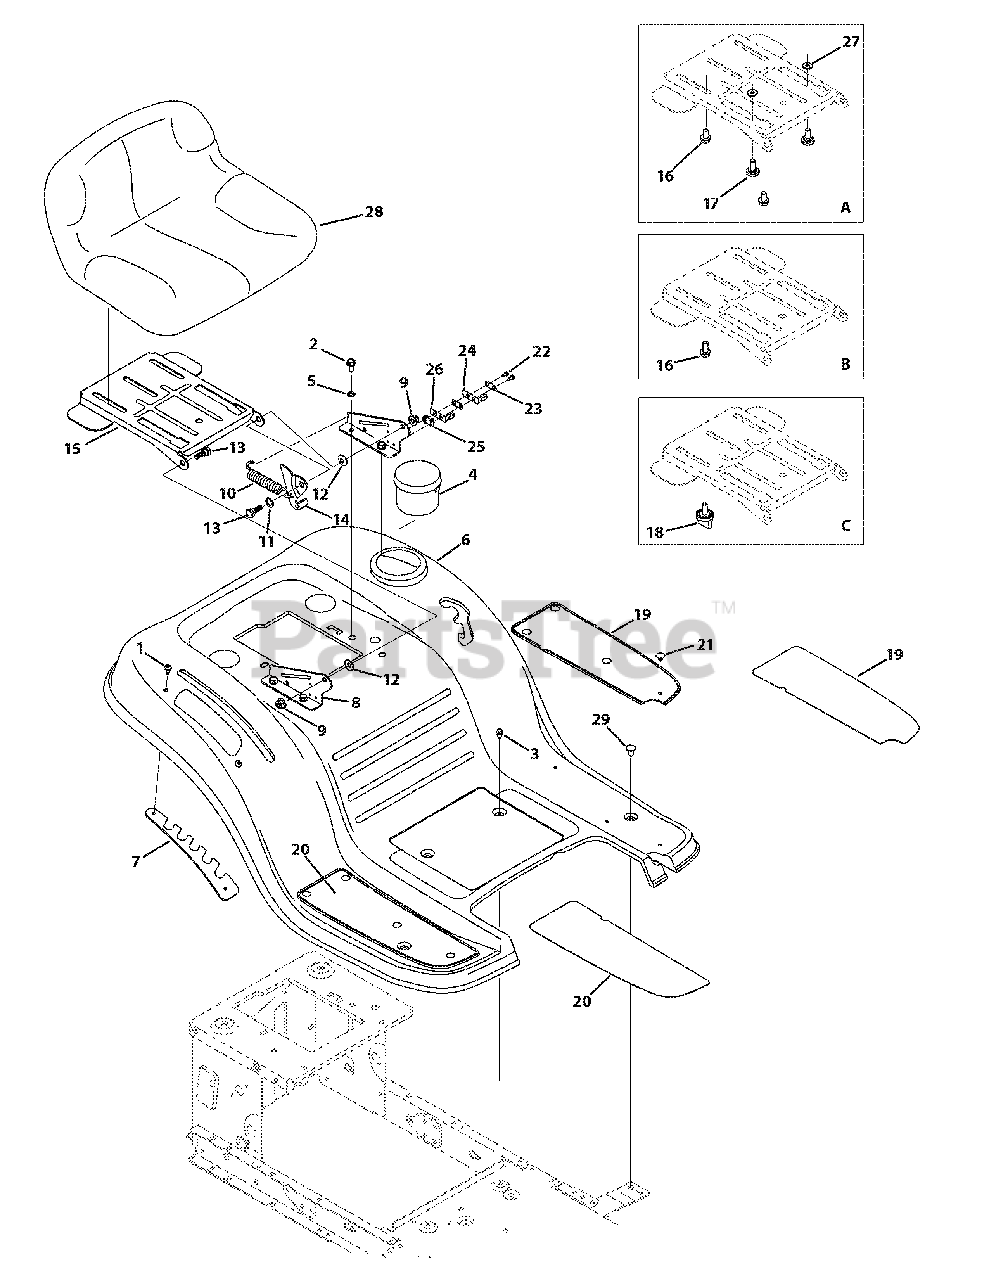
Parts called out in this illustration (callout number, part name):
1	Screw, 1/4-20 x .500
2	Screw, 5/16-18 x .750
3	Screw Pan Torx Head, 1/4-20 x .500
5	Lock Washer, 5/16
6	Fender - Red
7	Lift Adjuster Bracket - Powder Black
8	Seat Mount Bracket - Powder Black
9	Flangelock Nut, 5/16-18
10	Extension Spring
11	Flat Washer, .510x .750 x .033
12	Bell Washer, .340 x .872 x .060
13	Shoulder Screw, 5/16-18 x .437 x .268
14	Lift Seat Bracket
15	Pivot Seat Manual Adjust Bracket
16	Hex Head Flange, 3/8-16 x .875
17	Shoulder Screw, 3/8-16 x .625 x .145
18	Knob, 3/8-16 x .875
19	Foot Pad, LH
19	Foot Pad, Abrasive, LH
20	Foot Pad, RH
20	Foot Pad, Abrasive, RH
21	Ratchet Clip, .250 x .500
22	Screw, 8-18 x .500
23	Insulator Plate
24	Outer Seat Spring
25	Insulator Boss Plate
26	Inner Seat Spring
27	Flat Washer, .385 x .62 x .063
28	Low Back Seat, Black, Set-up B or C
29	Screw Carriage, 1/4-20 x .62
